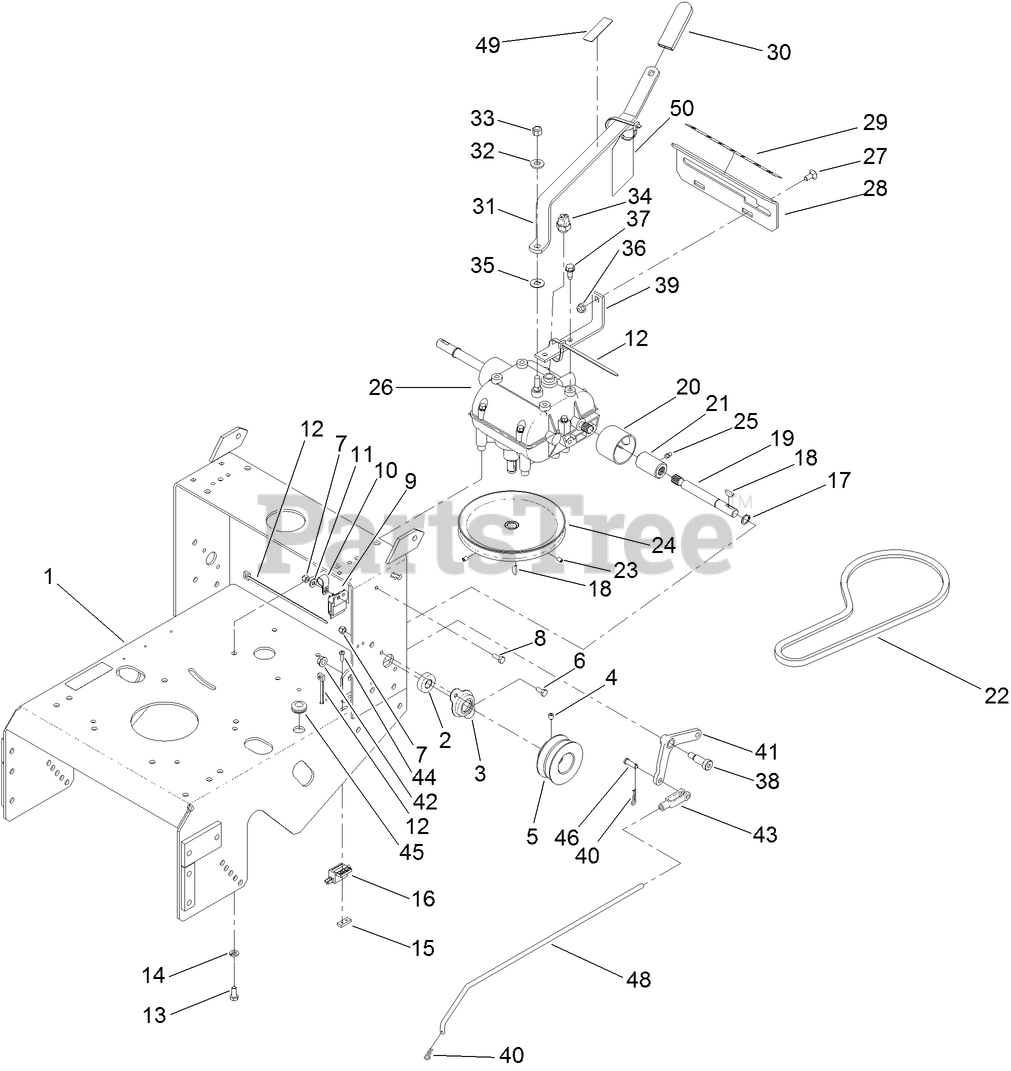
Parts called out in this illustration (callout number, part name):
1	FRAME-GEAR
2	BEARING-SHAFT
3	FLANGE-OUTPUT
4	SETSCREW
5	SHEAVE-TRANSMISSION
6	SCREW-HH
7	NUT-LOCK, NI
8	SCREW-HH
9	MODULE-INTERLOCK
10	CLIP-LOOM
11	WASHER-FLAT
12	TIE-PLASTIC
13	SCREW-HH
14	WASHER-LOCK
15	PLATE-TAPPED
16	SWITCH-OPEN, NORMALLY
17	RING-RETAINING
18	KEY-WOODRUFF
19	SHAFT-TRANSMISSION
20	GUARD-COUPLER
21	COUPLER
22	V-BELT
23	SCREW-HSH
24	SHEAVE-TRANSMISSION
25	FITTING-GREASE
26	TRANSMISSION-5 SPEED
27	BOLT-CARR
28	PLATE-SHIFT
29	DECAL-SPEED, GROUND
30	GRIP-LEVER
31	LEVER-SHIFT
32	WASHER-BELLEVILLE
33	NUT-LOCK
34	SWITCH-START, NEUTRAL
35	WASHER
36	NUT-HF, NI
37	SCREW-THD ROLL, HWH
38	BOLT-SHOULDER
39	BRACKET-PLATE, SHIFT
40	PIN-COTTER
41	BELLCRANK
42	NUT-HHF, WHIZ
43	YOKE-ADJUSTABLE
44	SCREW-PPH
45	GROMMET
46	PIN-CLEVIS
48	ARM-ASSIST, LINKAGE
49	DECAL-CAUTION, GEARBOX
50	HANG TAG-GEARBOX
